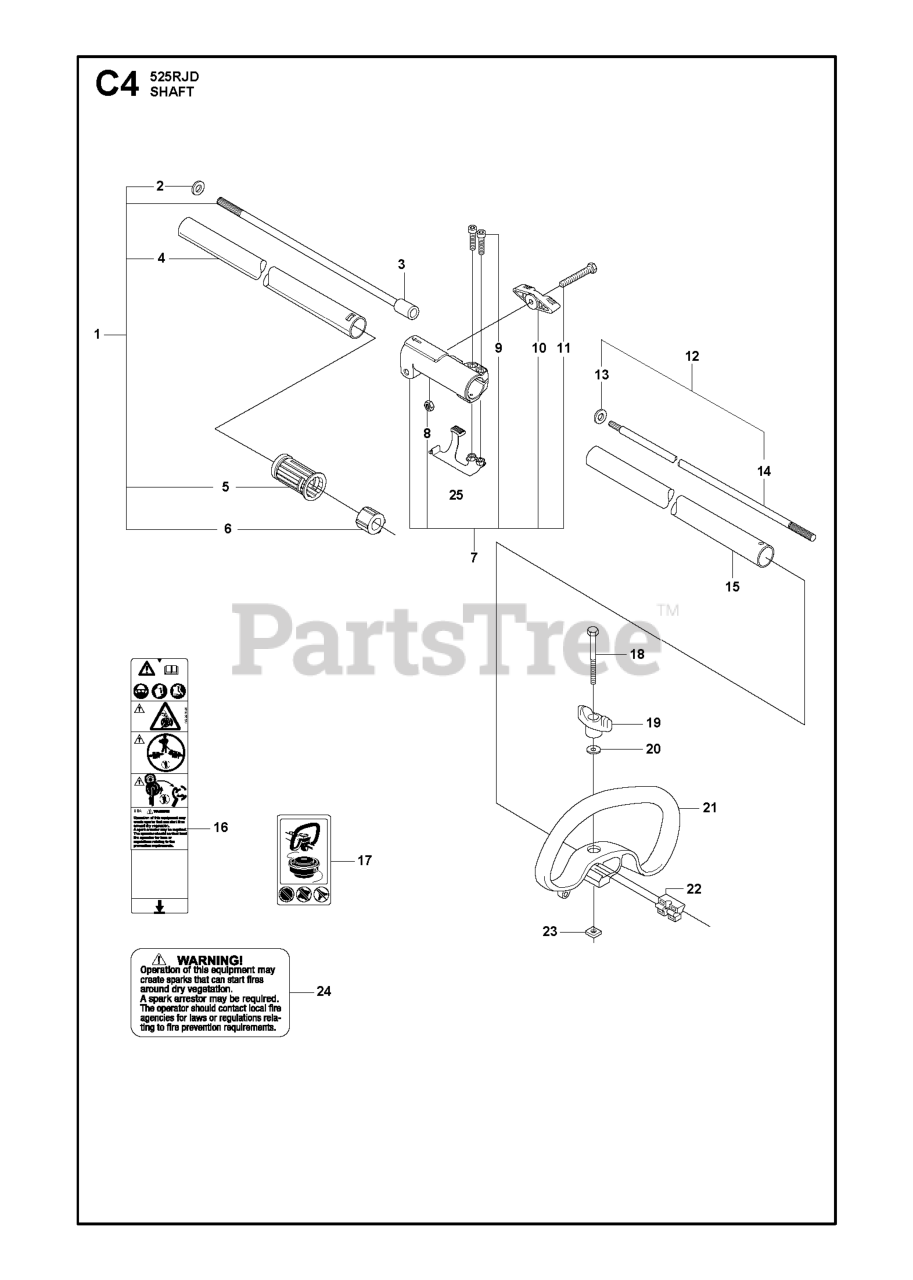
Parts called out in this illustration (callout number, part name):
3	SHAFT LOWER
5	PLUG
7	CLAMPING SLEEVE ASSY
10	KNOB CLAMPING SLEEVE
11	SCREW
12	DRIVE SHAFT COMPL
14	DRIVE SHAFT
16	LABEL WARNING TRIMMERS AND BRU
17	DECAL WARNING "NO BLADES"
18	BOLT
18	SCREW M6X50
19	KNOB
20	WASHER
22	SPACER PLASTIC
24	DECAL SPARK ARRESTOR WARNING
25	LOCKING PLATE ASSY CLAMPING SL
